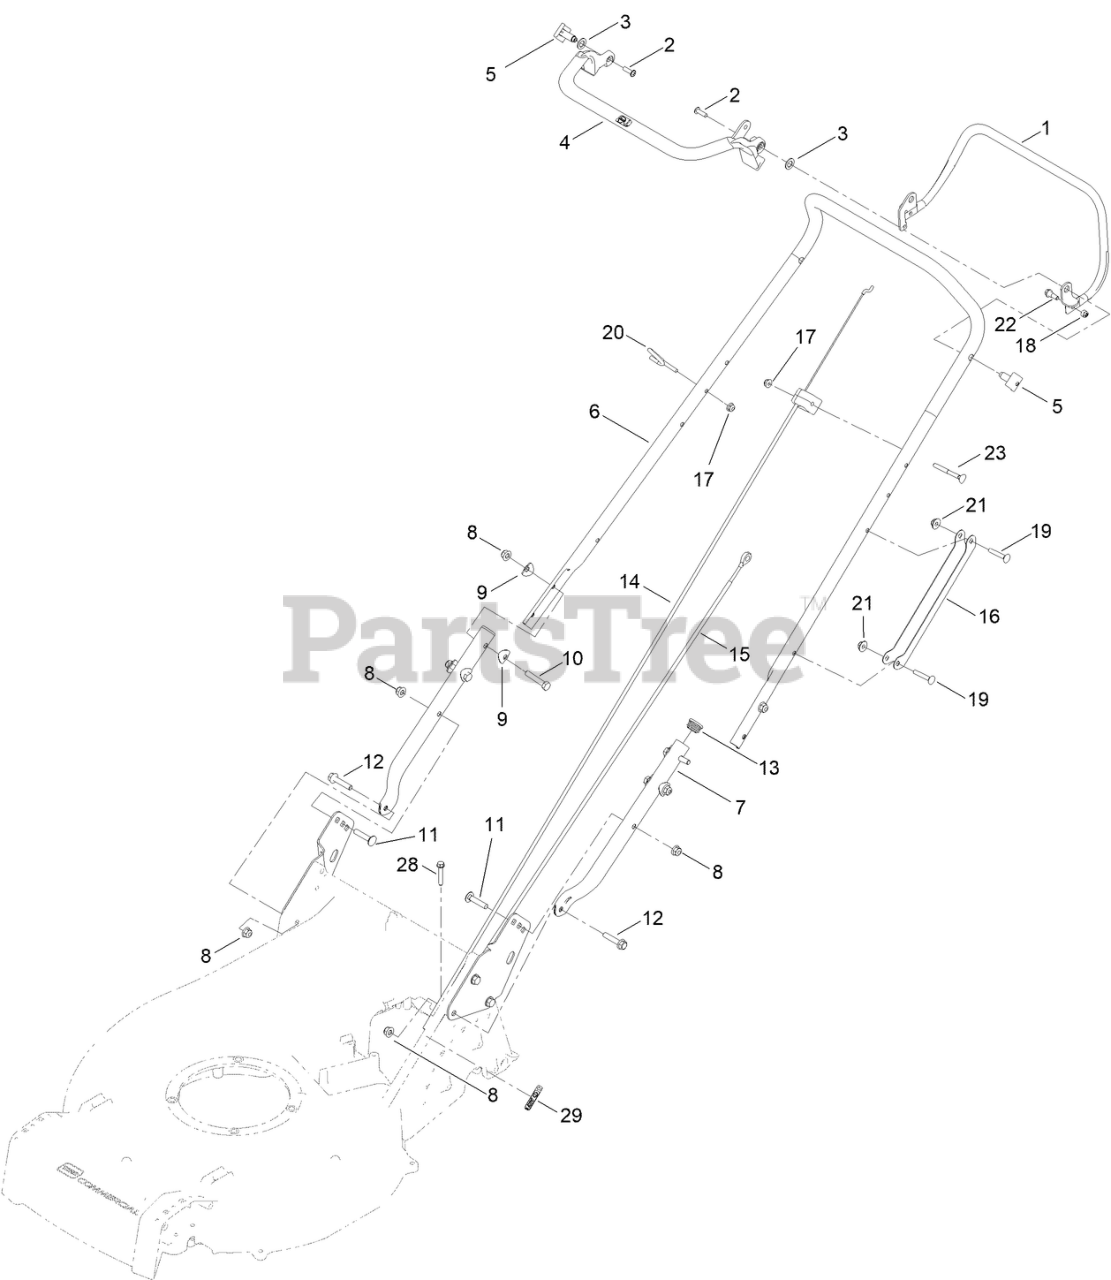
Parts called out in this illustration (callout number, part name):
1	LEVER-CLUTCH, GEARBOX
2	SCREW
3	WASHER-NYLON
4	OPC LEVER - ENGINE
5	PIN-PIVOT
6	HANDLE-UPPER
7	LOWER HANDLE
8	NUT-HF, NI
9	WASHER-CUP
10	SCREW-HH
11	BOLT-CARR
12	SCREW-HHF
13	PLUG-ROUND TUBE, 1 IN.
14	CABLE-TRACTION
15	CABLE-TRACTION, 60V
16	GUARD-CABLE, HANDLE
17	NUT-HF
18	NUT-NYLOC
19	SCREW-CARR
20	GUIDE-ROPE
21	NUT-HF
22	BOLT-SHOULDER
23	SCREW-HANDLE
28	SCREW-HWH
